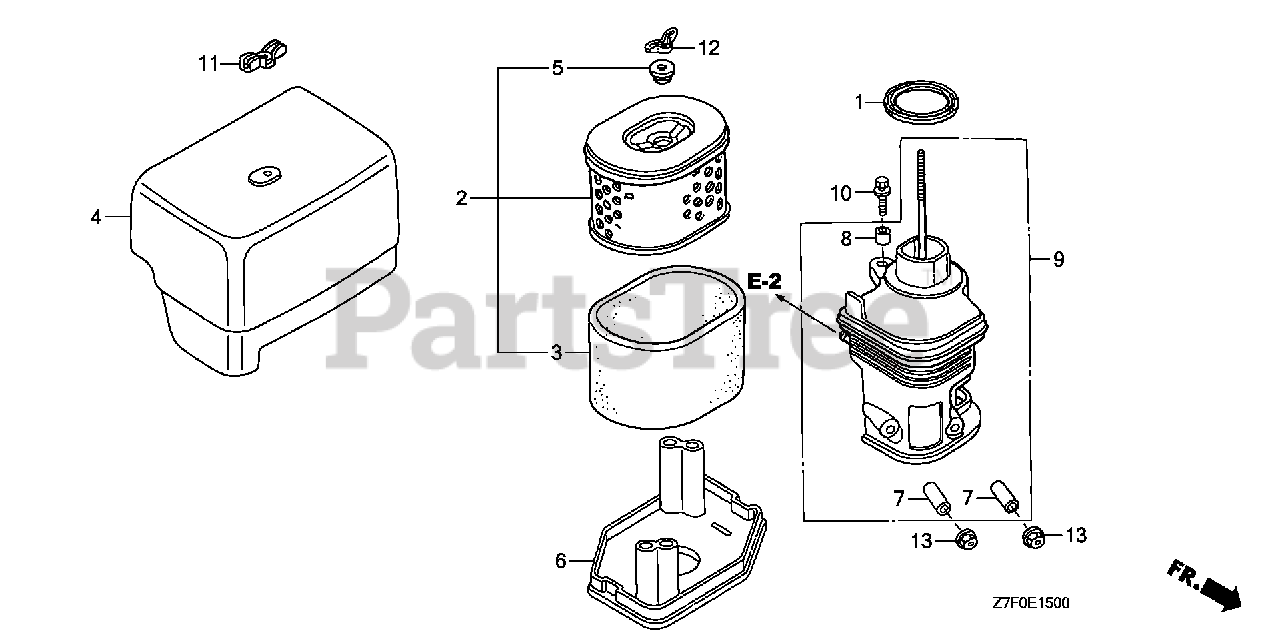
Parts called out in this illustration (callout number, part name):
1	GASKET, ELBOW
2	ELEMENT, AIR CLEANER
3	FILTER (OUTER)
4	COVER, AIR CLEANER
5	GROMMET, AIR CLEANER
6	NOSE, MUFFLER
7	COLLAR, AIR CLEANER
8	COLLAR B, AIR CLEANER
9	ELBOW, AIR CLEANER
10	BOLT-WASHER (6X22)
11	WINGNUT (6MM) (BLACK)
12	NUT, TOOL BOX SETTING
13	NUT, FLANGE (6MM)
